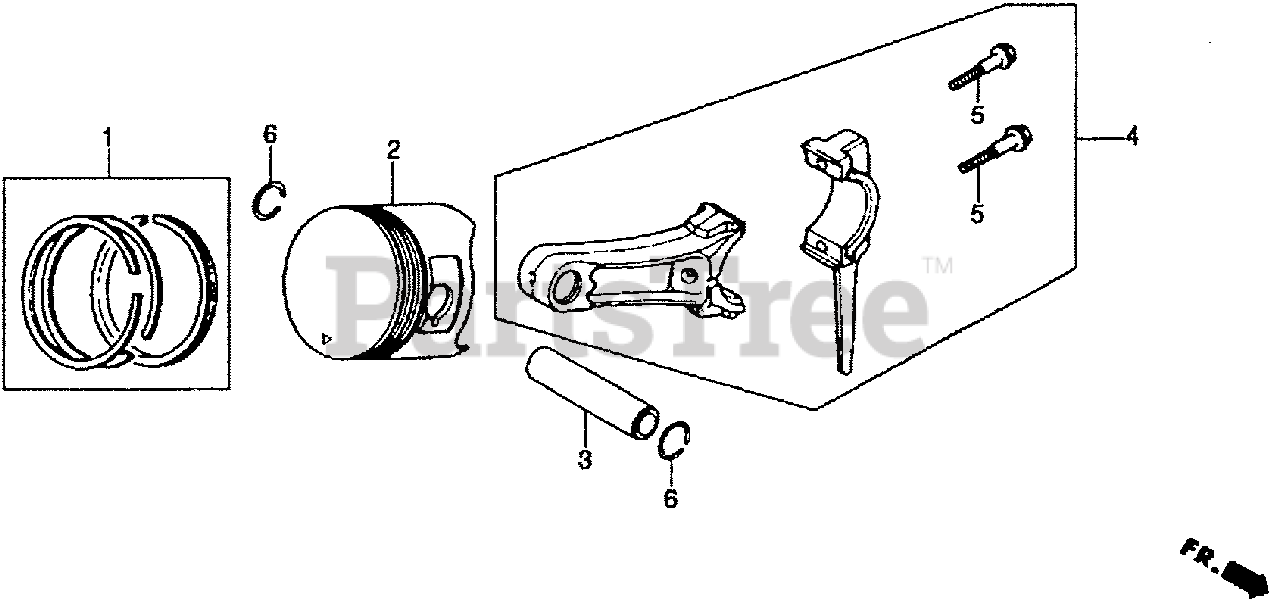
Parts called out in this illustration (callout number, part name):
1	RING SET, PISTON (STD)
1	RING SET, PISTON (OS 0.25)
1	RING SET, PISTON (OS 0.50)
1	RING SET, PISTON (0.75)
2	PISTON (STD)
2	PISTON (OS 0.25)
2	PISTON (OS 0.50)
2	PISTON (0.75)
3	PIN, PISTON
4	ROD ASSY., CONNECTING (US 0.25)
4	ROD ASSY., CONNECTING
5	BOLT, CONNECTING ROD
6	CLIP, PISTON PIN (18MM)
